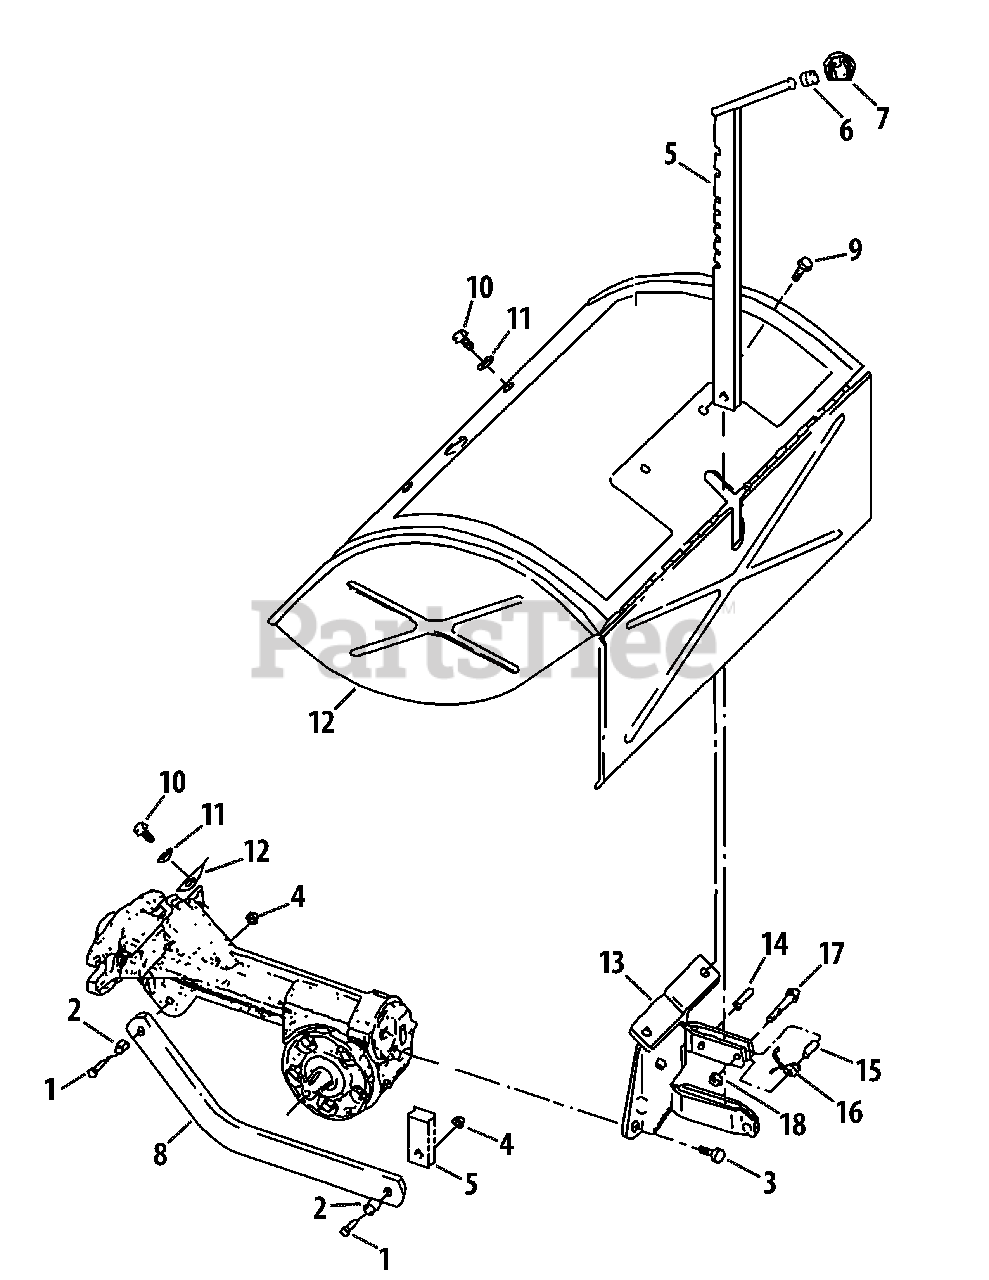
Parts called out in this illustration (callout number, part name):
1	Hex Bolt, 3/8"-16 x 1-1/4"
2	Bushing Spacer, .5 x .375 x .3
3	Hex Flange Bolt, 5/16"-18 x .625
4	Flangelock Nut, 3/8"-16
5	Depth Regulator
6	Retaining Ring
7	Depth Regulator Knob
8	Depth Regulator Bar Drag
9	Thread-forming Screw, 1/4"-20 x 1/2"
10	Hex Flange Bolt, 5/16"-18
11	Washer, 1.12 x .34 x .06
13	Hood Bracket
14	Roll Pin (Spirol), 1/4" x 1"
15	Split Spacer
17	Hex Bolt, 1/4"-20 x 1"
18	Locknut, 1/4"-20
